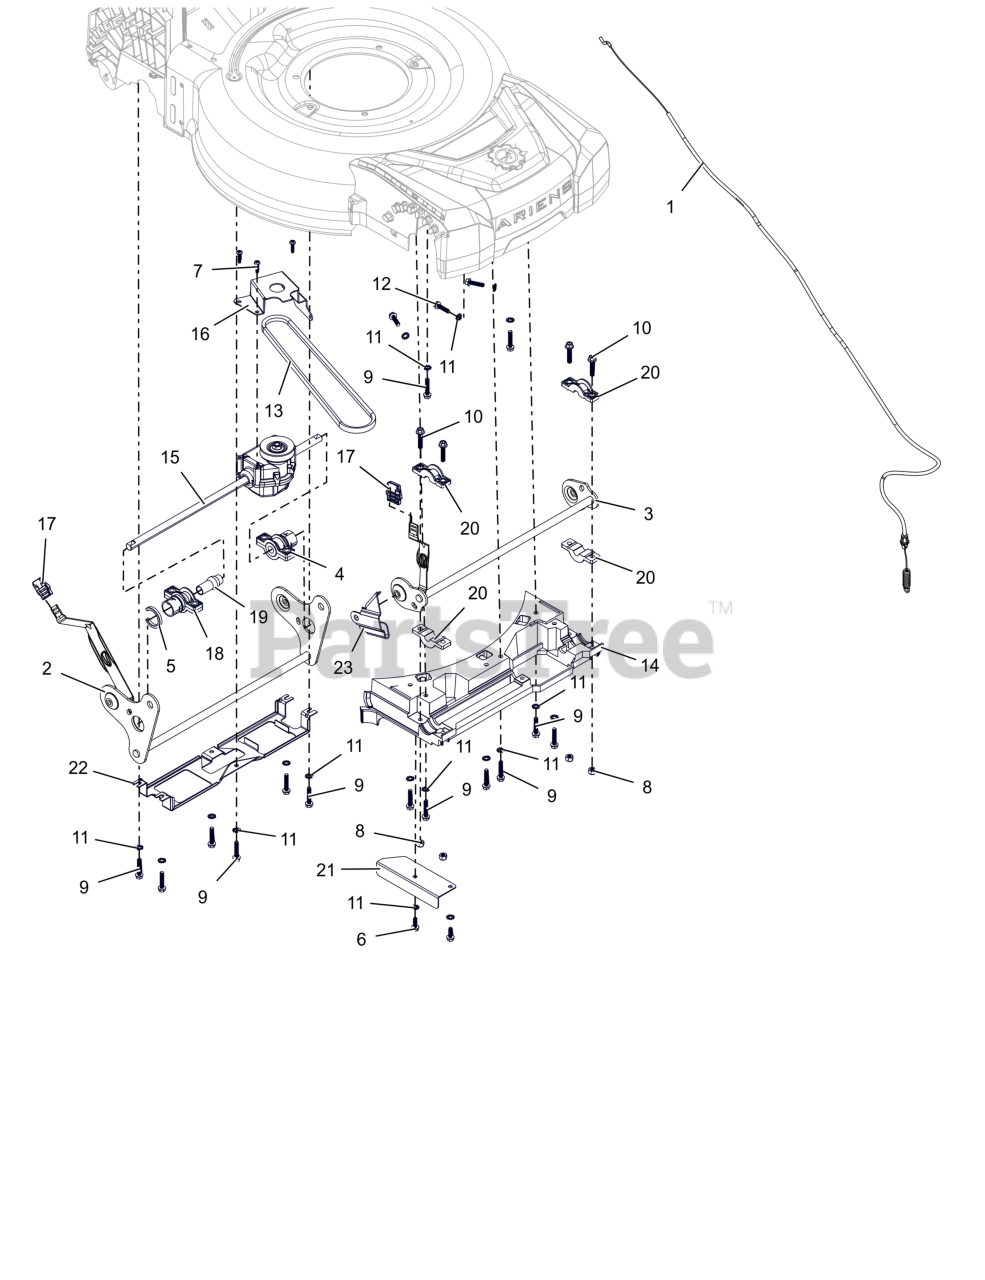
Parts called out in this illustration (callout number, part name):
1	CABLE, RWD TRANSMISSION
2	WLDMT, REAR AXLE - RWD (BLACK)
3	WLDMT, FRONT AXLE - PUSH (BLACK)
4	ASM, BSHG - BRONZE
5	CLIP, OUTER BUSHING
6	SCR, HI-LO HWH 1/4-15 X .750
7	SCR, TORX TRILOB PH 10-14X.75
8	NUT, NYLOC 1/4-20
9	SCR, HI-LO HWH 1/4-15 X 1.25
10	BLT, HWH 1/4-20 X 1.25
11	WSHR-LK-EXT, .256X.510X.028
12	SCR, HI-LO HWH 1/4-15 X 1.00
13	BELT, RWD
14	TRAY, FRONT
15	ASM, RWD TRANSMISSION - MA 302
16	BRKT, RWD TRANSMISSION (BLACK)
17	GRIP, HOC
18	BUSHING, AXLE - OUTER
19	BUSHING, AXLE - INNER
20	BUSHING, SHAFT - HOC
21	FLANGE, BLOW OUT (BLACK)
22	BRKT, RWD BACK SUPPORT (BLACK)
23	BRKT, ARM SUPPORT (BLACK)
